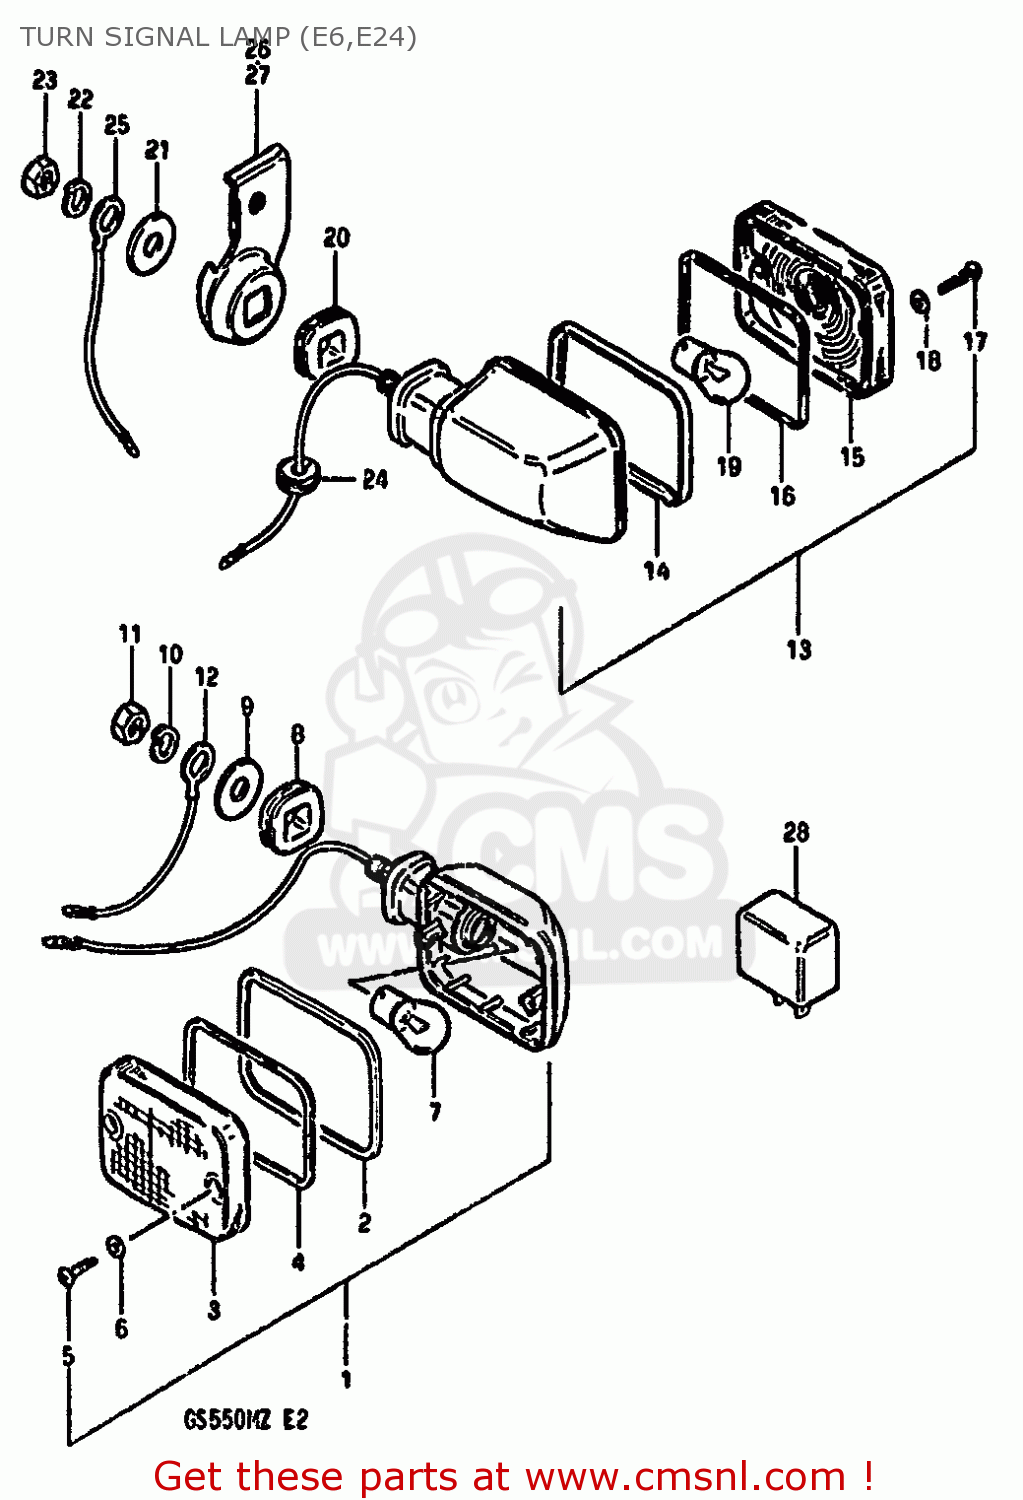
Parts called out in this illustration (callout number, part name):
1	LAMP ASSEMBLY,FRONT TURN SIGNAL
2	RIM
3	LENS
4	GASKET (NAS)
5	SCREW
6	GASKET (NAS)
7	BULB(12V23W,STANLEY,A4577A)
8	CUSHION
9	WASHER (10.5X30X2.3)
10	LOCK WASHER
11	NUT
12	WIRE
13	LAMP ASSEMBLY,FRONT TURN SIGNAL
14	RIM
15	LENS
16	GASKET (NAS)
17	SCREW
18	GASKET (NAS)
19	BULB(12V23W,STANLEY,A4577A)
20	CUSHION
21	WASHER (10.5X30X2.3)
22	LOCK WASHER
23	NUT
24	GROMMET
25	WIRE
26	BRACKET,REAR TURN SIGNAL
27	BRACKET,REAR TURN SIGNAL
28	RELAY,TURN SIGNAL
